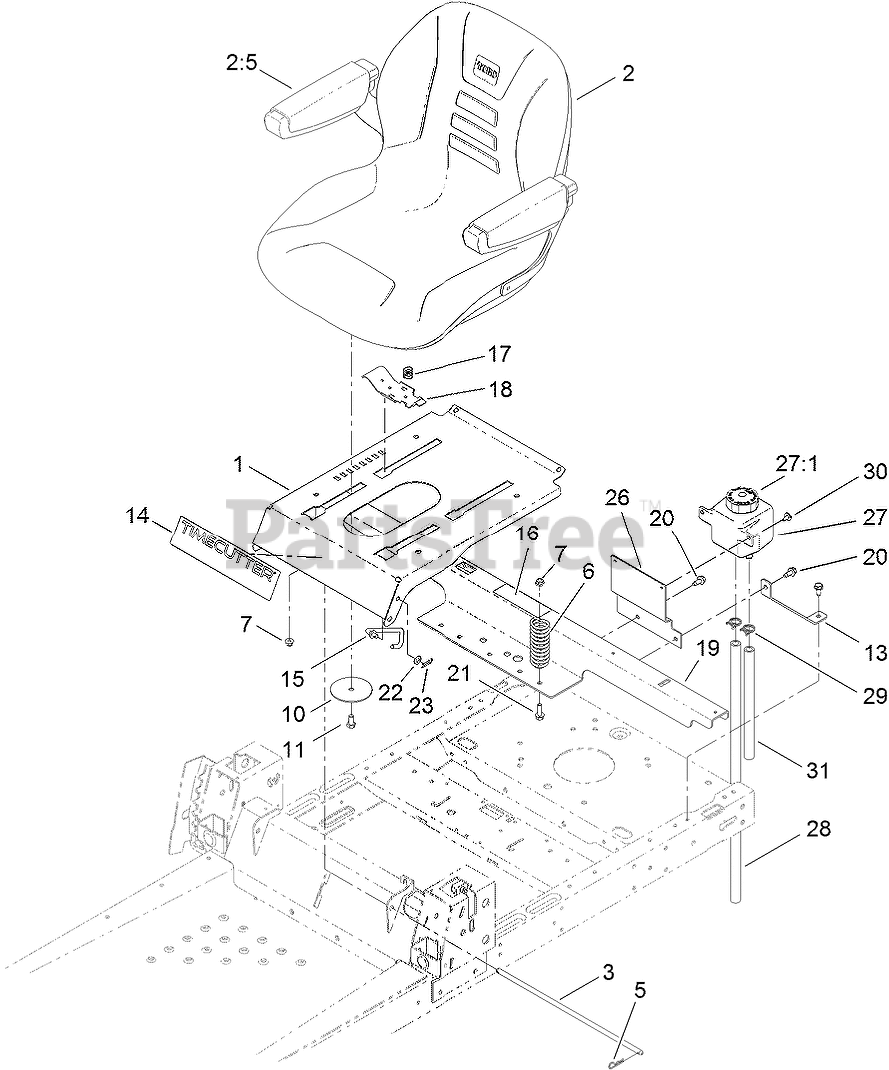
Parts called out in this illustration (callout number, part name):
1	PAN-SEAT
2	18 INCH SEAT ASM
2:5	ARMREST KIT
3	ROD-STOP
5	PIN-COTTER
6	SPRING-COMPRESSION
7	NUT-HF, NI
10	WASHER-SEAT
11	SCREW-HH
13	SUPPORT-TANK, REAR
14	DECAL-TIMECUTTER
15	STOP-SEAT
16	DECAL-SERVICE, CE
17	SPRING-COMPRESSION
18	LATCH-SEAT
19	SUPPORT-POD
20	SCREW-HWHTF
21	SCREW-HHF
22	WASHER-PLAIN
23	PIN-COTTER
26	MOUNT-TANK
27	VENT-TANK, HYD
27:1	CAP-RESERVOIR, HYD
28	HOSE-OVERFLOW
29	CLAMP-HOSE
30	SCREW-HHFTF
31	HOSE-OVERFLOW
